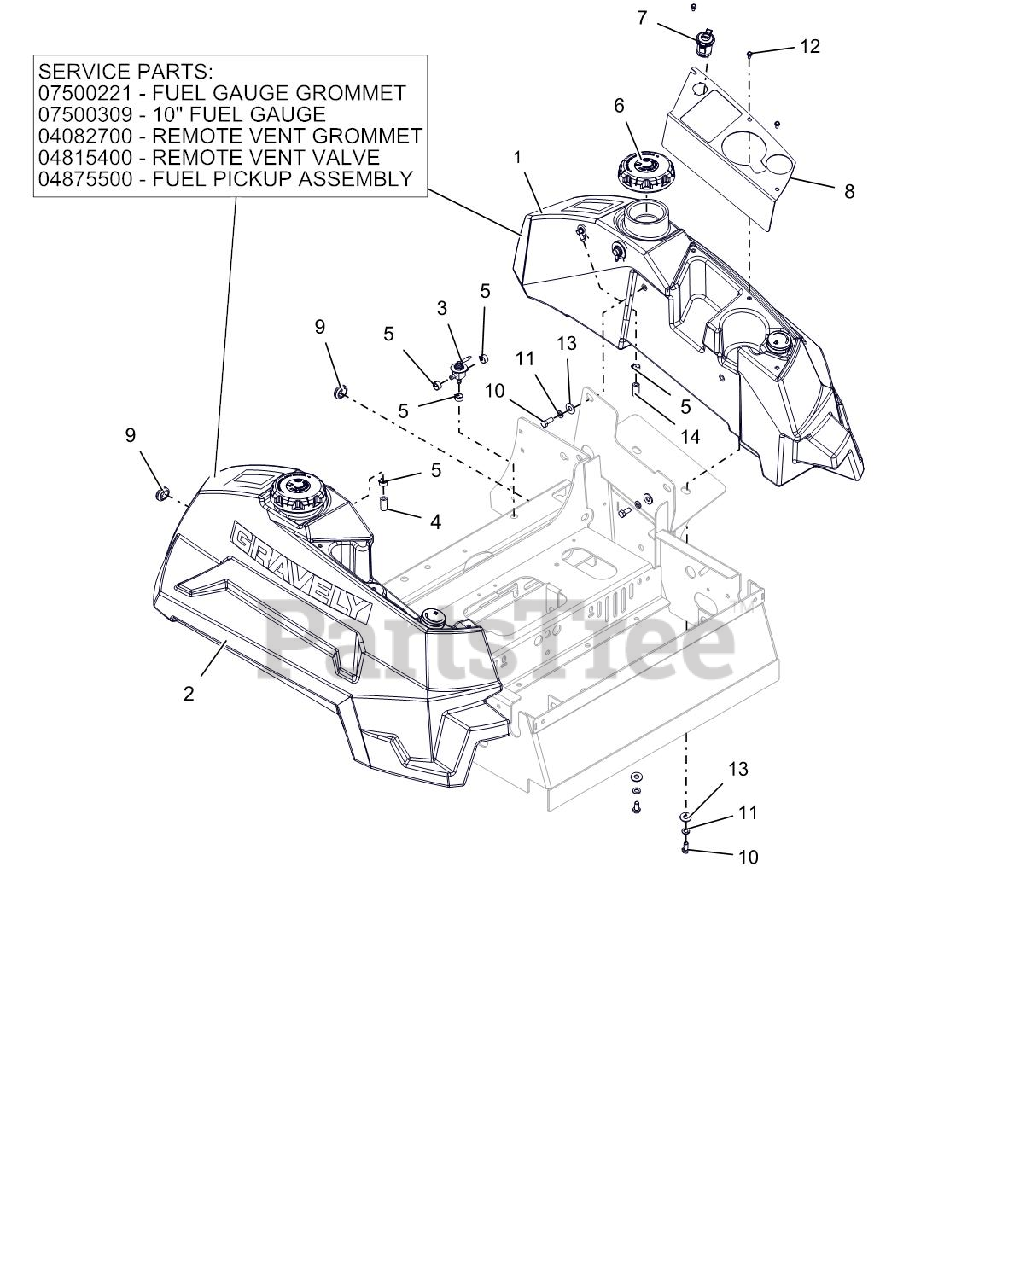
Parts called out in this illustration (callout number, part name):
1	ASM, PT200/400 LH FUEL TANK
2	ASM, PT200/400 RH FUEL TANK
3	VALVE - FUEL
4	HOSE, .25 LOW-PERM BULK GAS
5	CLAMP, FUEL LINE
6	CAP, FUEL NONVENT AUTOLOCK
7	PORT, 12 VOLT POWER
8	CUP HOLDER/POCKET PLATE - RED
9	GROMMET,RUBBER 5/8 ID/1.13 OD
10	@BLT-HEX .31-18X.75 GR5 YWZC
11	@WSHR-LK .31X.078 REG YWZC
12	SCR-MCH 10-24X.38 HWHSTAINLESS
13	@WSHR-FL-STL.38X.875X.083 YWZC
14	HOSE, .25 LOW-PERM BULK GAS
15	GROMMET, FUEL GAUGE
16	GAUGE, REMOTE FUEL SEALED 10"
17	GROMMET, REMOTE VENT NITRILE
18	VALVE, 2-WAY
19	ASSM,LRG TANK FUEL PICKUP LINE
